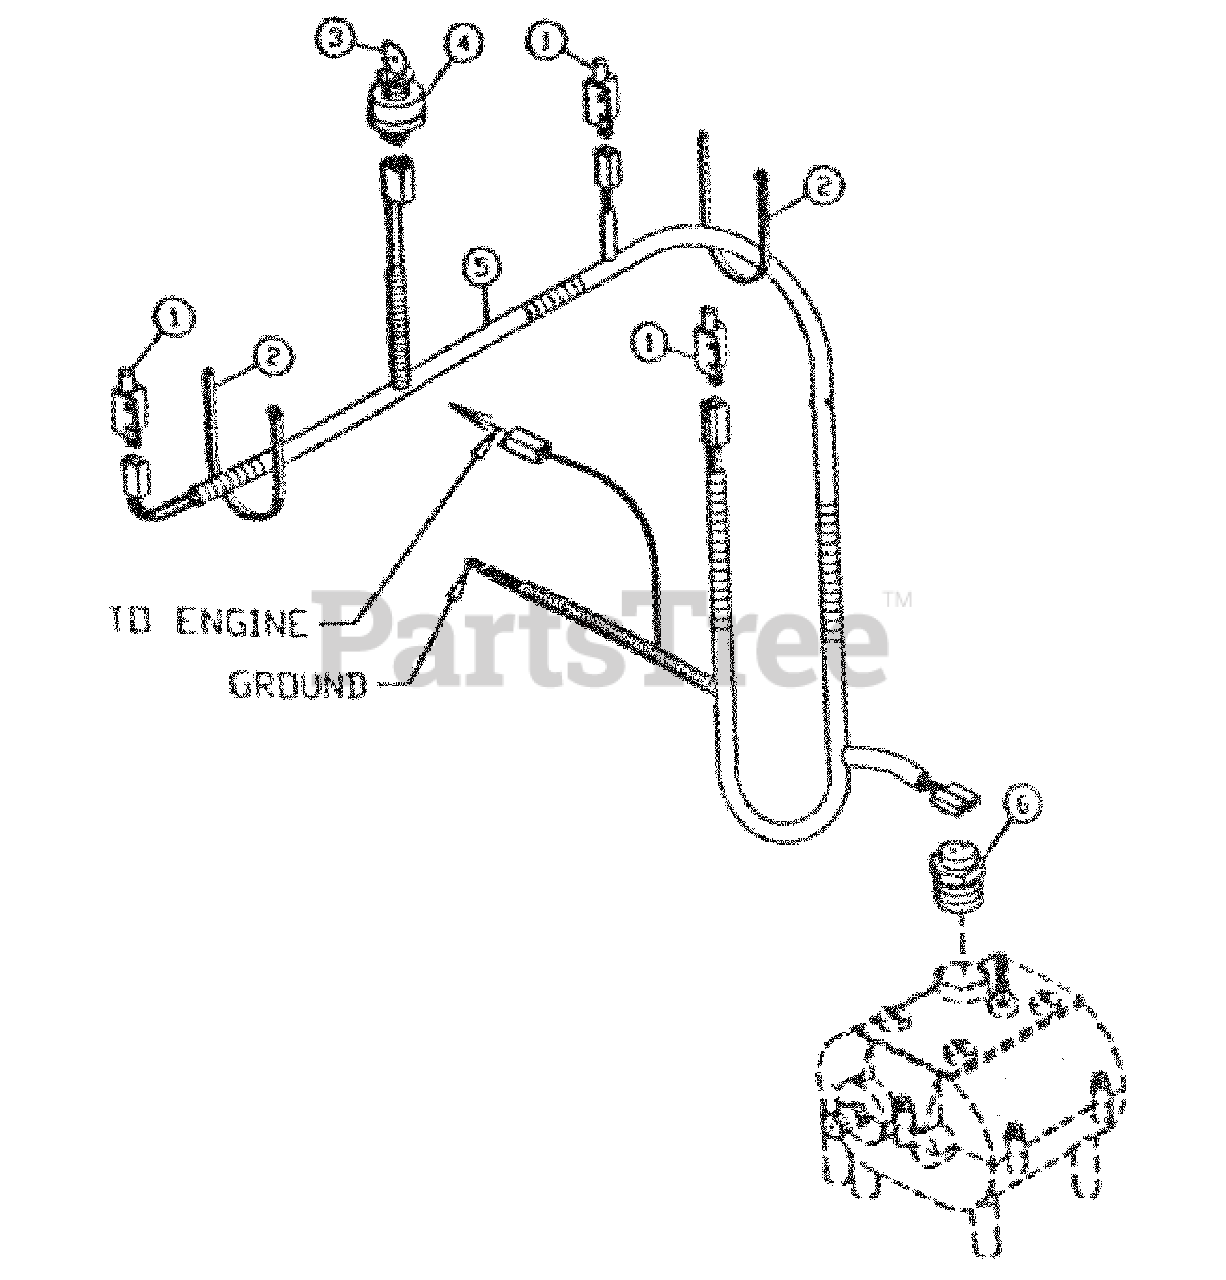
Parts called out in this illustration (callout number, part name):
1	100-060 SWITCH
3	100-114 KEY SWITCH & KEY
4	100-114 KEY SWITCH & KEY
5	100-115 WIRING HARNESS
6	100-055 NEUTRAL SWITCH
